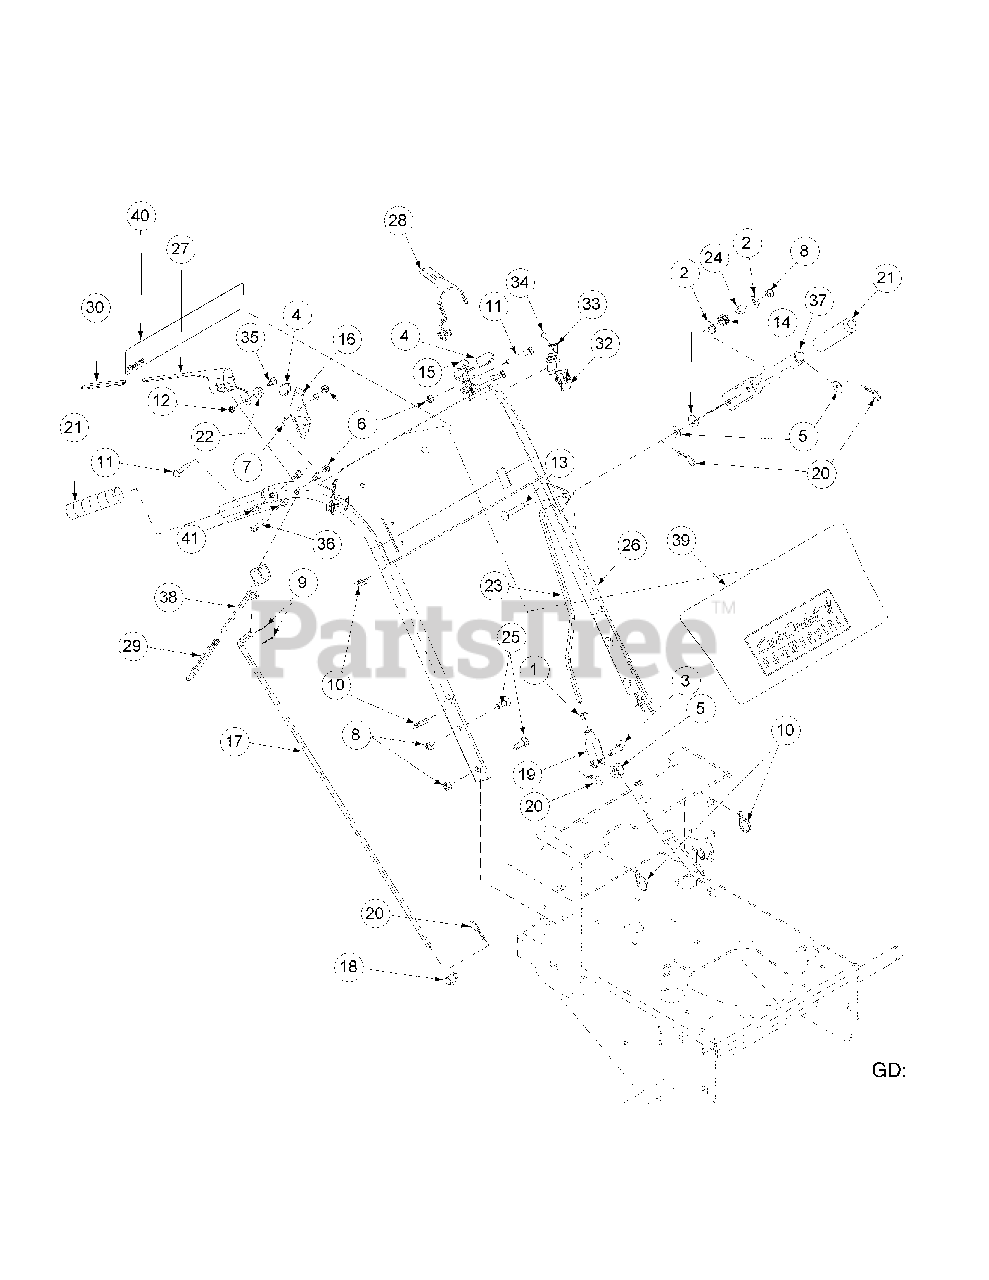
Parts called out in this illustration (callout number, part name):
1	Hex Nut, 3/8-16
2	Flat Washer, 3/8 Zinc
3	Clevis Pin, 3/8 x 1-1/8 Zinc
4	Grip, Neutral Latch, 1.25"
5	Flat Washer, 3/8 Zinc
6	Nylock Nut, 5/16-18
7	Flat Washer, 5/16 Zinc
8	Lock Nut, Nylon Insert, 3/8-16
9	Cotter Pin, 3/32 x 3/4, Zinc
10	Cable Tie, 3/16 x .05 x 7.4
11	Hex Cap Screw, 5/16-18 x 2
12	Lock Nut, Nylon Insert
13	Carriage Bolt, 3/8-16 x 2
14	Spring, .850 OD x 1
15	Neutral Latch, Left Hand
16	Neutral Latch, Right Hand
17	Steering Control Rod
18	Joint Swivel
19	Yoke, 3/8-16 Female
20	Hair Pin 3/8-1/2
21	Handle Grip, Black, 1"
22	Control Rod, Hydro Spacer
23	Blade Clutch Rod
24	Spring Sleeve
25	Carriage Bolt, 3/8-16 x 2
26	Handle Assembly
27	Operator Presence Control RH
28	Operator Presence Control LH
29	Control Sleeve, Black
30	Operator Control Sleeve, Yellow
31	Harness Assembly Adapter (not show)
32	Switch Mounting Snap
33	Operator Presence Return Spring
34	Hex Index Washer Screw, 0.500
35	Shoulder Screw, .38 x .412, 1/4-28
36	Hex Cap Screw, 5/16-18, 2.00
37	Blade Clutch Lever
38	Lever Assembly Control
39	Label Commercial Mower Panel
40	Label Commercial Mower Instruction
41	Nylon Bushing
